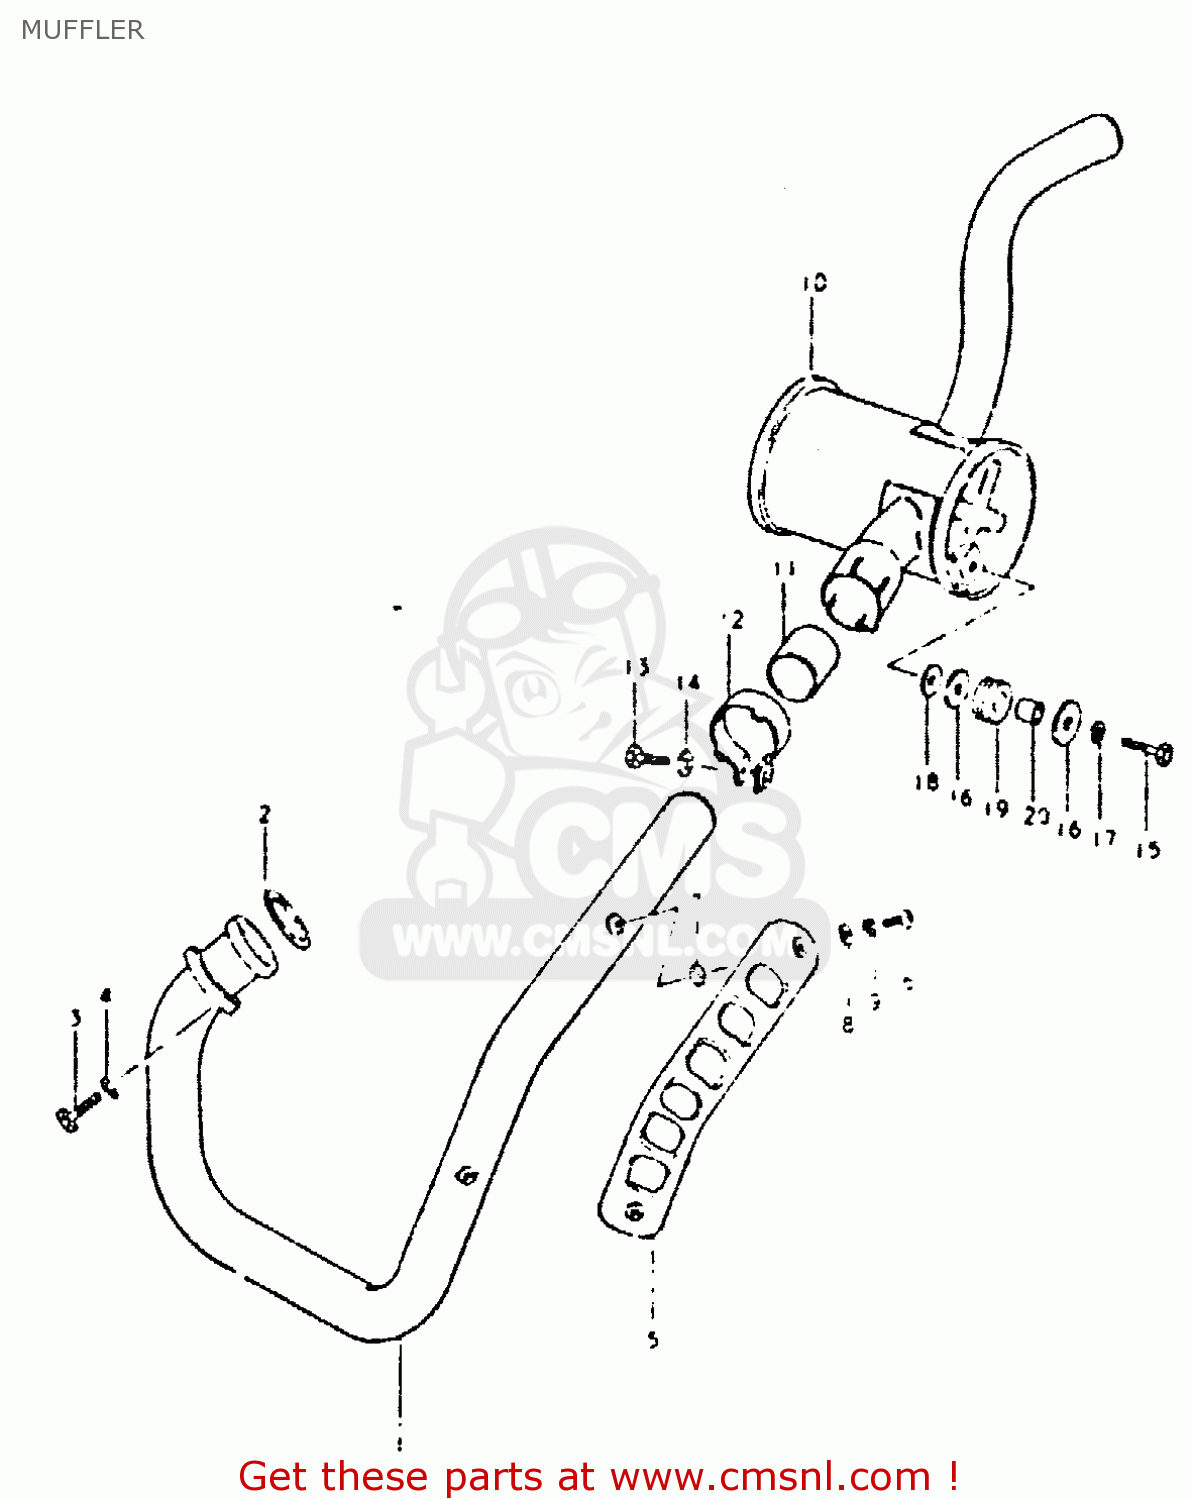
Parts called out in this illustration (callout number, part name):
1	PIPE,EXHAUST
2	GASKET,EXHAUST PIPE (NAS)
3	BOLT (8X30)
4	LOCK WASHER
5	COVER,EXHAUST PIPE
6	SCREW
7	GASKET 6.2X12X1.5 (MCA)
8	WASHER
9	LOCK WASHER
10	BODY,MUFFLER
11	CONNECTOR,MUFFLER
12	CLAMP,MUFFLER CONNECTOR
13	BOLT 8X35
14	WASHER
15	BOLT (8X30)
16	WASHER (8.5X29X1.6)
17	LOCK WASHER
18	GASKET
19	CUSHION
20	SPACER (8.6X13.8X13)
